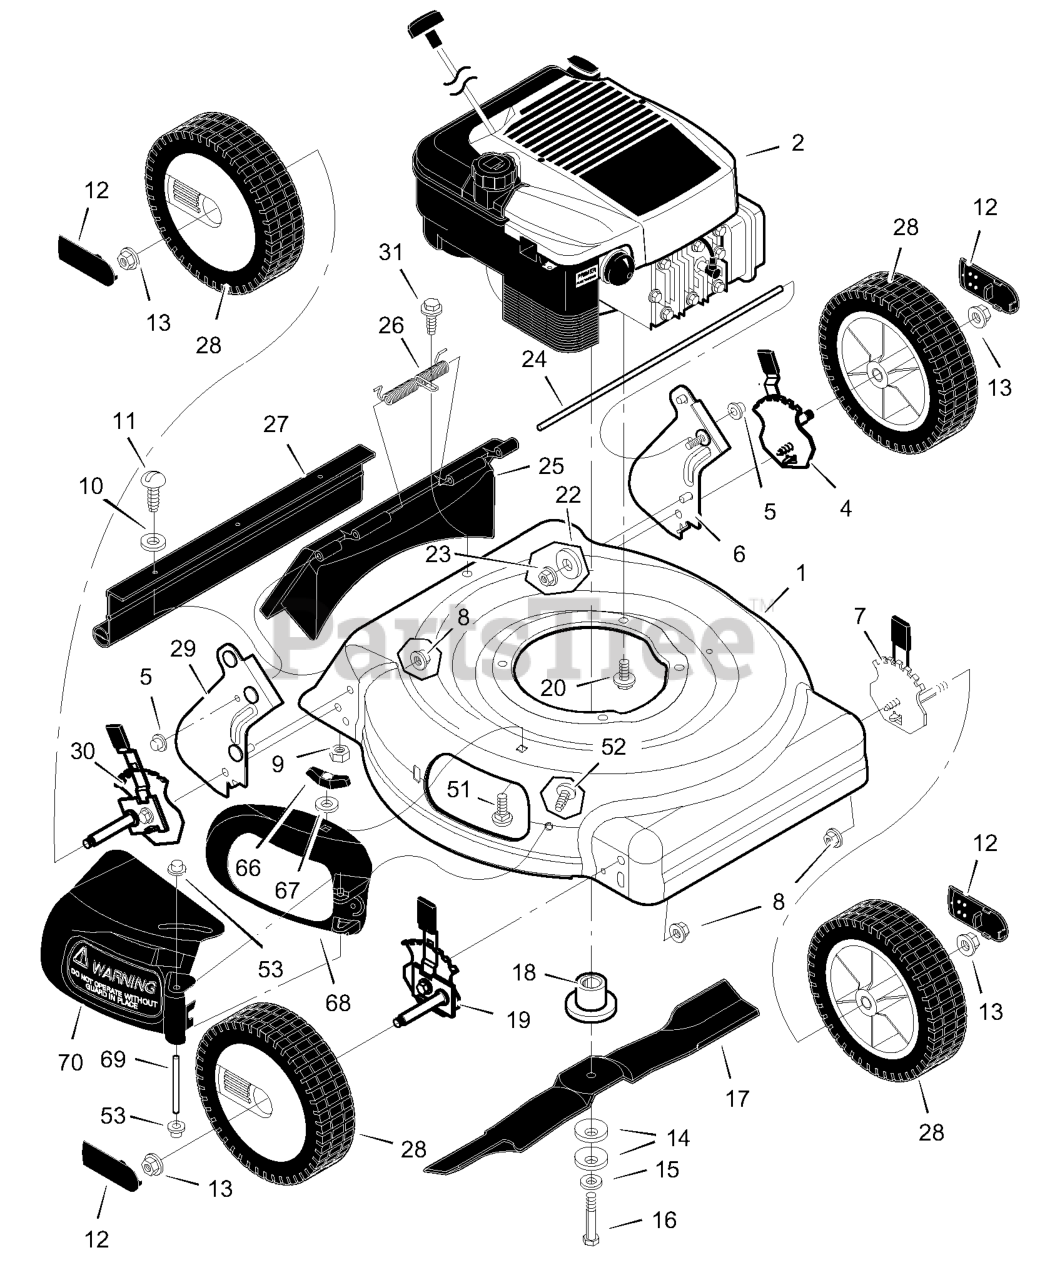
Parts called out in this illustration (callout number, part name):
1	Housing
2	Engine
4	Adjuster, Left Rear Height
5	Push On Cap
6	Bracket, Left Handle
7	Adjuster, Left Front Height
8	Nut, Flange
9	Nut, Hex
12	Hub Cap
13	Nut, Flange
14	Washer, Belleville
18	Adapter, Blade
19	Adjuster, Right Front Height
20	Bolt, Engine
22	Washer
23	Nut, Flange
24	Rod, Pivot
25	Door, Rear
27	Guard, Rear
28	Wheel
29	Bracket, Right Handle
30	Adjuster, Right Rear Height
51	Bolt, Carriage
53	Push On Cap
66	Wingnut
67	Retainer, Push
69	Pin, Pivot
70	Deflector, Chute
